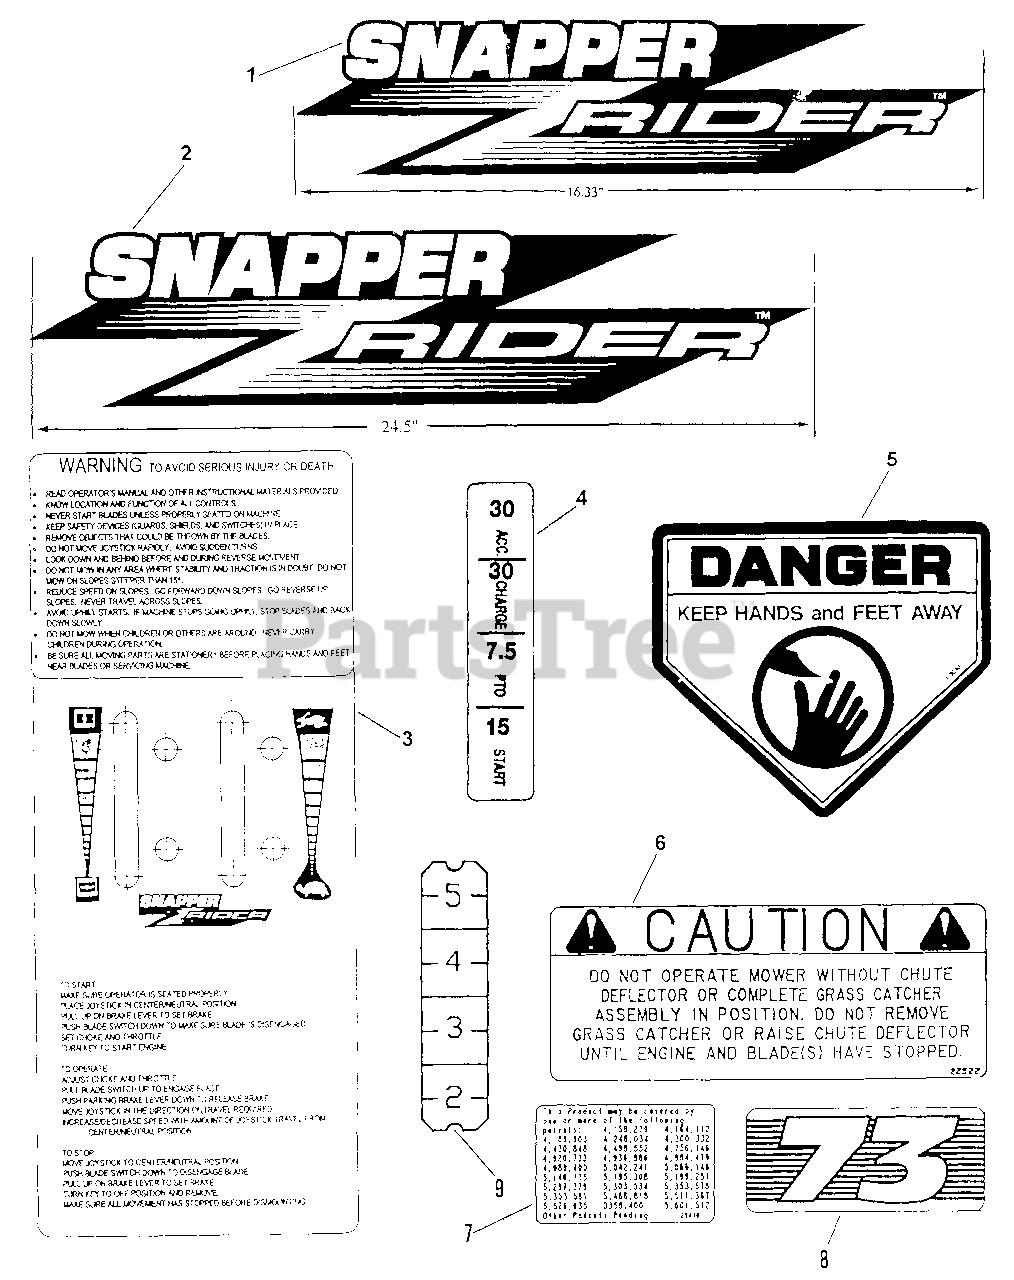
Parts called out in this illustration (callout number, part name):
1	LOGO, Front 16 33" Long
2	LOGO, Side 24.5" Long
3	DECAL, Throttle/Choke
4	DECAL, Fuse
5	DECAL, Warning (CPSC Cut-Finger)
6	DECAL, Warning
7	DECAL, Patent Numbers
9	DECAL, Height-of-Cut
